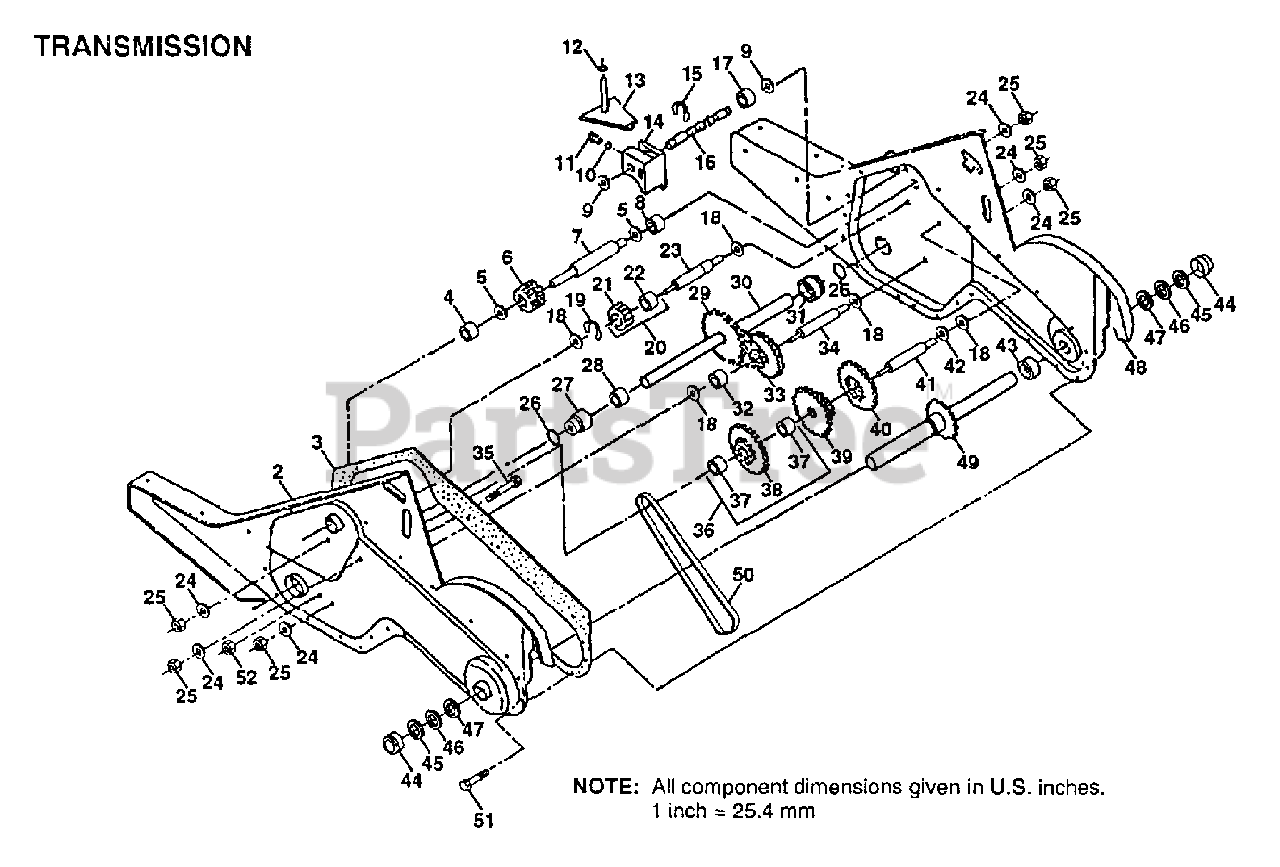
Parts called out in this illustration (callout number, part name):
3	GASKET TI
4	NEEDLE BRNG LT
5	"T, BEARING"
6	PINION-INPUT CRT
7	SHAFT-INPUT CRT
8	"TI, BEARING"
9	WASHER SEAL CRT
11	SPRING-SHIFT CRT
12	O-RING TI
13	ARM ASSY CRT
14	SHIFT FORK TI
15	KLIP RING
16	SHAFT SHIFT CRT
17	SPACER SPLIT CRT
18	WASHER
19	KLIP RING
20	GEAR ASSY CRT
21	GEAR-REV IDLR CRT
22	NEEDLE BEARING TI
23	SHAFT CRT
24	LOCKWASHER
25	NUT.ASF.HEX.7/16
26	O RING CRT
27	"CRT, BEARING"
28	BUSHING TI
29	CHAIN CRT
32	SPACER TI
33	SPRCKT 8 GEAR CRT
34	SHFT 2ND RED. CRT
35	SCRW WHIZ LOK CRT
36	SPROCKET ASM.
37	BEARING
39	GEAR TI
40	GEAR TI
41	REDUCTION SHFT TI
42	BRNG RACE
43	SPACER TI
44	CUP.FORMED.
45	RING SPIRAL CRT
49	TINE SHAFT
50	CHAIN.50 LINK TI
51	SCREW CRT
52	NUT.HEX.5/16-18
